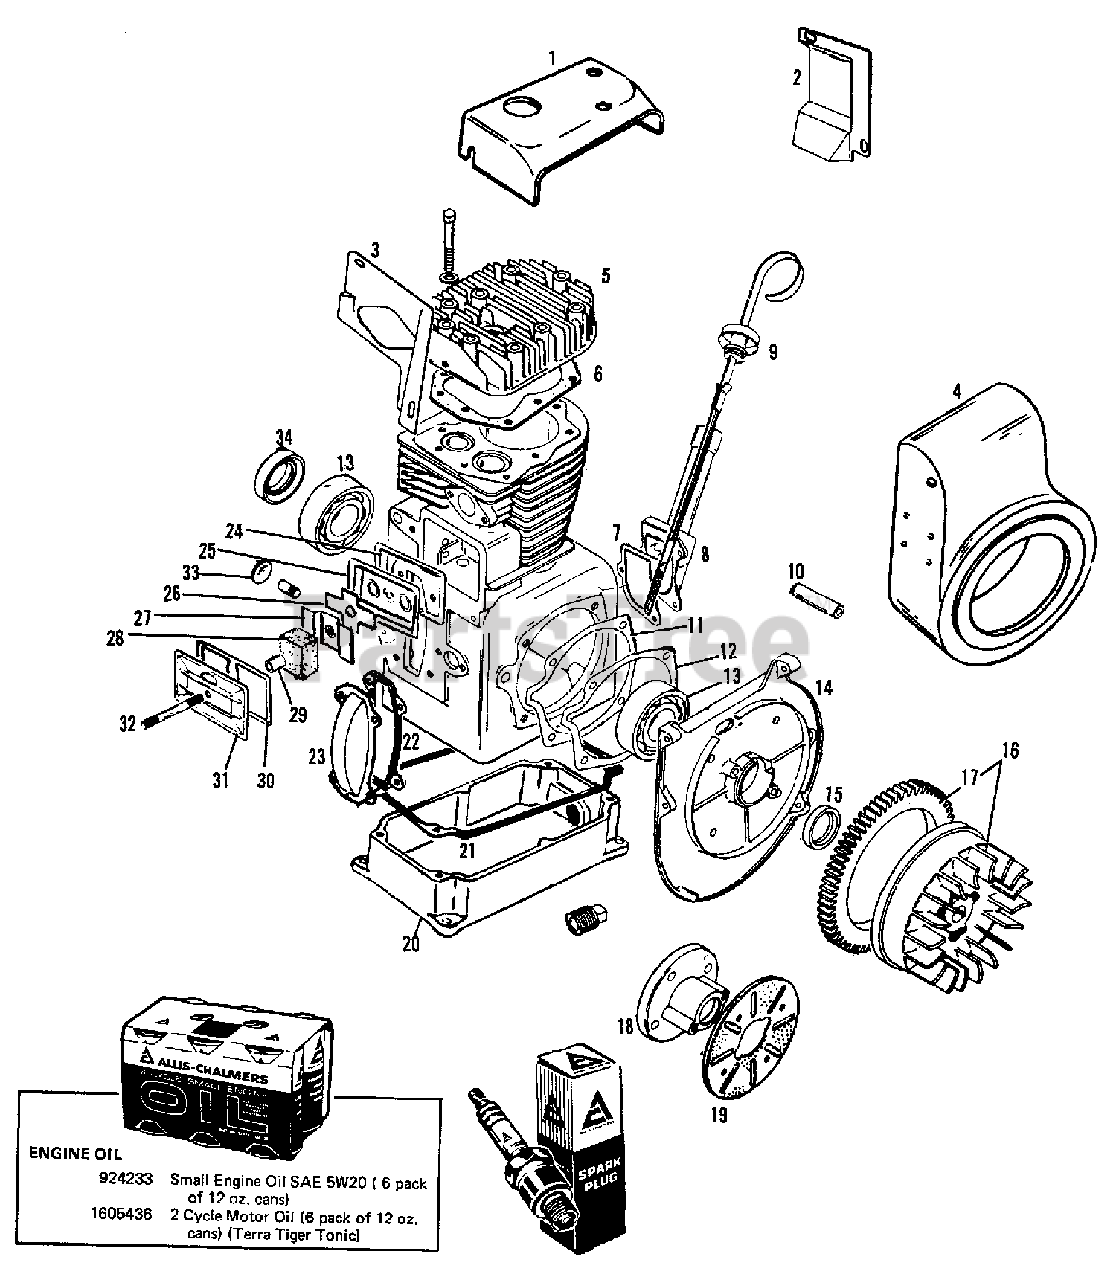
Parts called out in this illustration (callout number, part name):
1	BAFFLE, Head (10 & 14 H.P.)
1	BAFFLE, Head (16 H.P.)
1	SCREW, 1/4NC x 1/2
2	BAFFLE, Cylinder (10 & 14 H.P.)
2	BAFFLE, Cylinder (16 H.P.)
3	BAFFLE, Side
4	HOUSING, Blower
4	SCREW, 1/4NC x 3/4
5	HEAD, Cylinder (10 H.P.)
5	HEAD, Cylinder (14 H.P.)
5	HEAD, Cylinder (16 H.P.)
5	SCREW, 3/8NC x 1-1/2
5	WASHER, 25/64 x 27/32 x 1/8
6	GASKET, Head (10 H.P. & 14 H.P.) (Included In Engine Gasket Set)
6	GASKET, Head (16 H.P.) (Included In Engine Gasket Set)
7	GASKET, Dipstick Tube (Included In Engine Gasket Set)
8	TUBE ASSEMBLY, Dipstick Oil Gauge
8	LOCKWASHER, #10 Intermediate Tooth
9	DIPSTICK ASSEMBLY, Oil Level
10	SHAFT, Stub Crankcase
11	GASKET, .10 (Use As Required) (Included In Engine Gasket Set)
12	GASKET, Bearing Plate (Included In Engine Gasket Set)
13	BEARING ASSEMBLY, Ball
14	PLATE ASSEMBLY, Bearing (10 H.P.)
14	PLATE ASSEMBLY, Bearing (16 H.P.)
15	SEAL, Front Oil (Included In Engine Gasket Set)
16	FLYWHEEL ASSEMBLY, (Includes RING GEAR)
17	GEAR, Ring
18	ADAPTER, Front Drive
18	SCREW, 3/8NC x 7/8
18	WASHER, 1/4
18	NUT, Lock, 5/8NC
18	SCREW, 1/4NC x 5/8 (Truss Head)
18	LOCKWASHER, 1/4 (Internal Tooth)
19	SCREEN, Grass
20	PLUG, Pipe, 3/4
20	CAPSCREW, 3/8NC x 1-1/4
20	CAPSCREW, 3/8NC x 1-1/2
21	GASKET, Oil Pan (Included In Engine Gasket Set)
22	GASKET, Camshaft Cover (Included In Engine Gasket Set)
23	COVER, Camshaft
23	SCREW, 1/4NC x 1/2
24	GASKET, Breather Plate (Included In Engine Gasket Set)
25	PLATE, Breather
26	REED, Breather
27	BAFFLE, Breather
28	FILTER, Breather
29	SEAL, Breather (Included In Engine Gasket Set)
30	GASKET, Breather Valve Cover (Included In Engine Gasket Set)
31	COVER, Valve Breather
32	STUD, Breather
32	NUT, 1/4NC
33	PLUG, Expansion
34	SEAL, Rear Oil (Included In Engine Gasket Set
34	BEARING, Needle
34	*GASKET SET, Engine (16 H.P.)
34	PLUG, Spark
